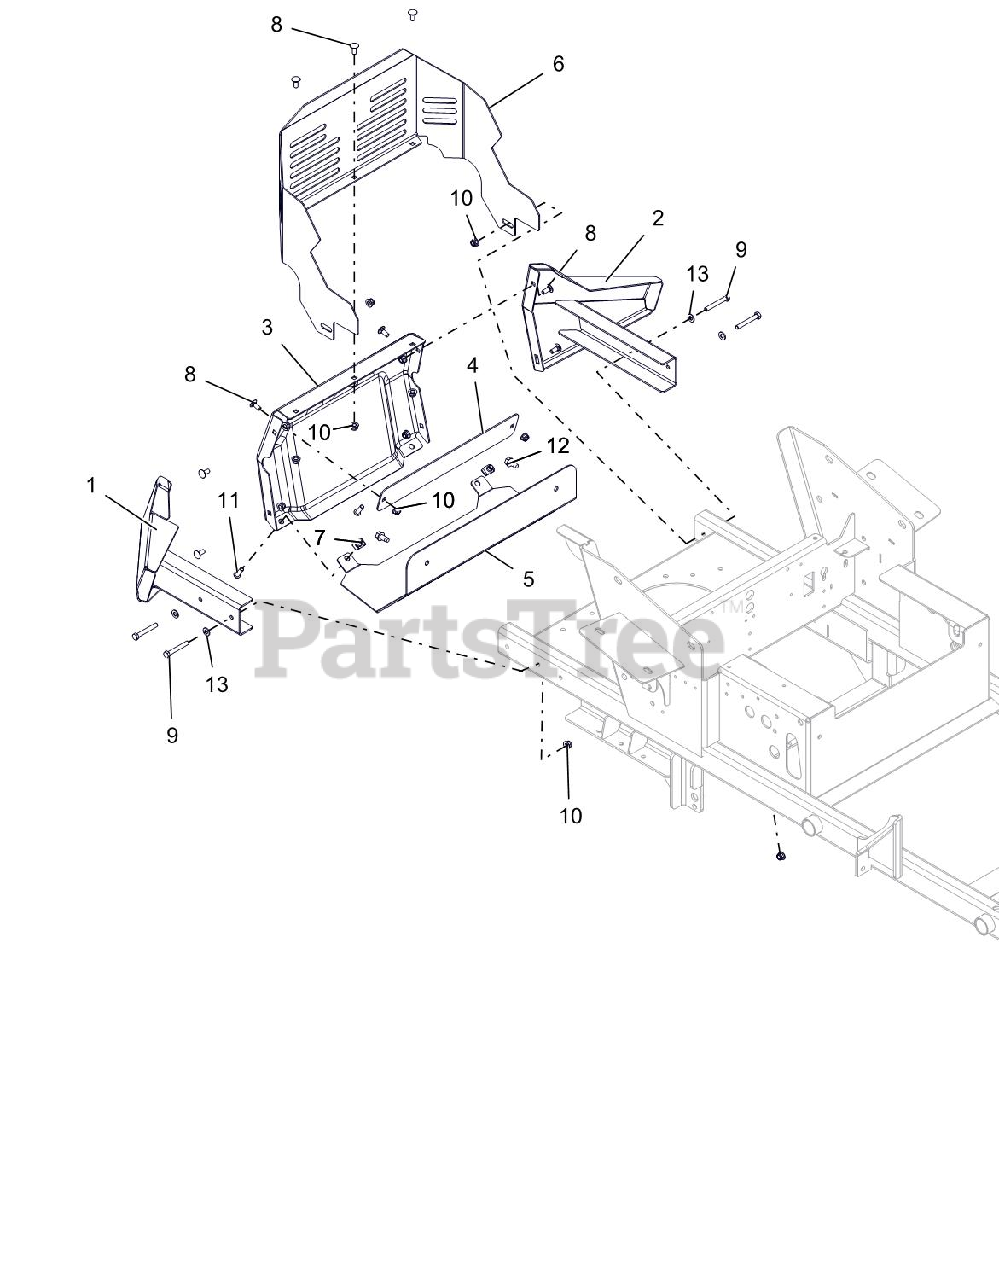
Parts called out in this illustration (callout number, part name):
1	RH REAR BUMPER WING W/SAFETY DECAL
2	LH REAR BUMPER WING W/SAFETY DECAL
3	BUMPER, PT200/400 REAR
4	PLATE, BACKER
5	GUARD, PT100 MUFFLER
6	GUARD, PT100 ENGINE
7	NUT-CLIP RETAINER 5/16-18X.56
8	BOLT, CARRIAGE 0.3125-18X0.75 GR5
9	BOLT, HEX 0.313-18X2.25 GR5
10	NUT-LK-NYL-FLG .31-18 YWZC
11	SCR-SKH .31-18X1.00 BTNHD YWZC
12	SCR-TAP .38-16X.75 HWH TR YWZ
13	WSHR-FL-STL.344X.688X.065YWZC
